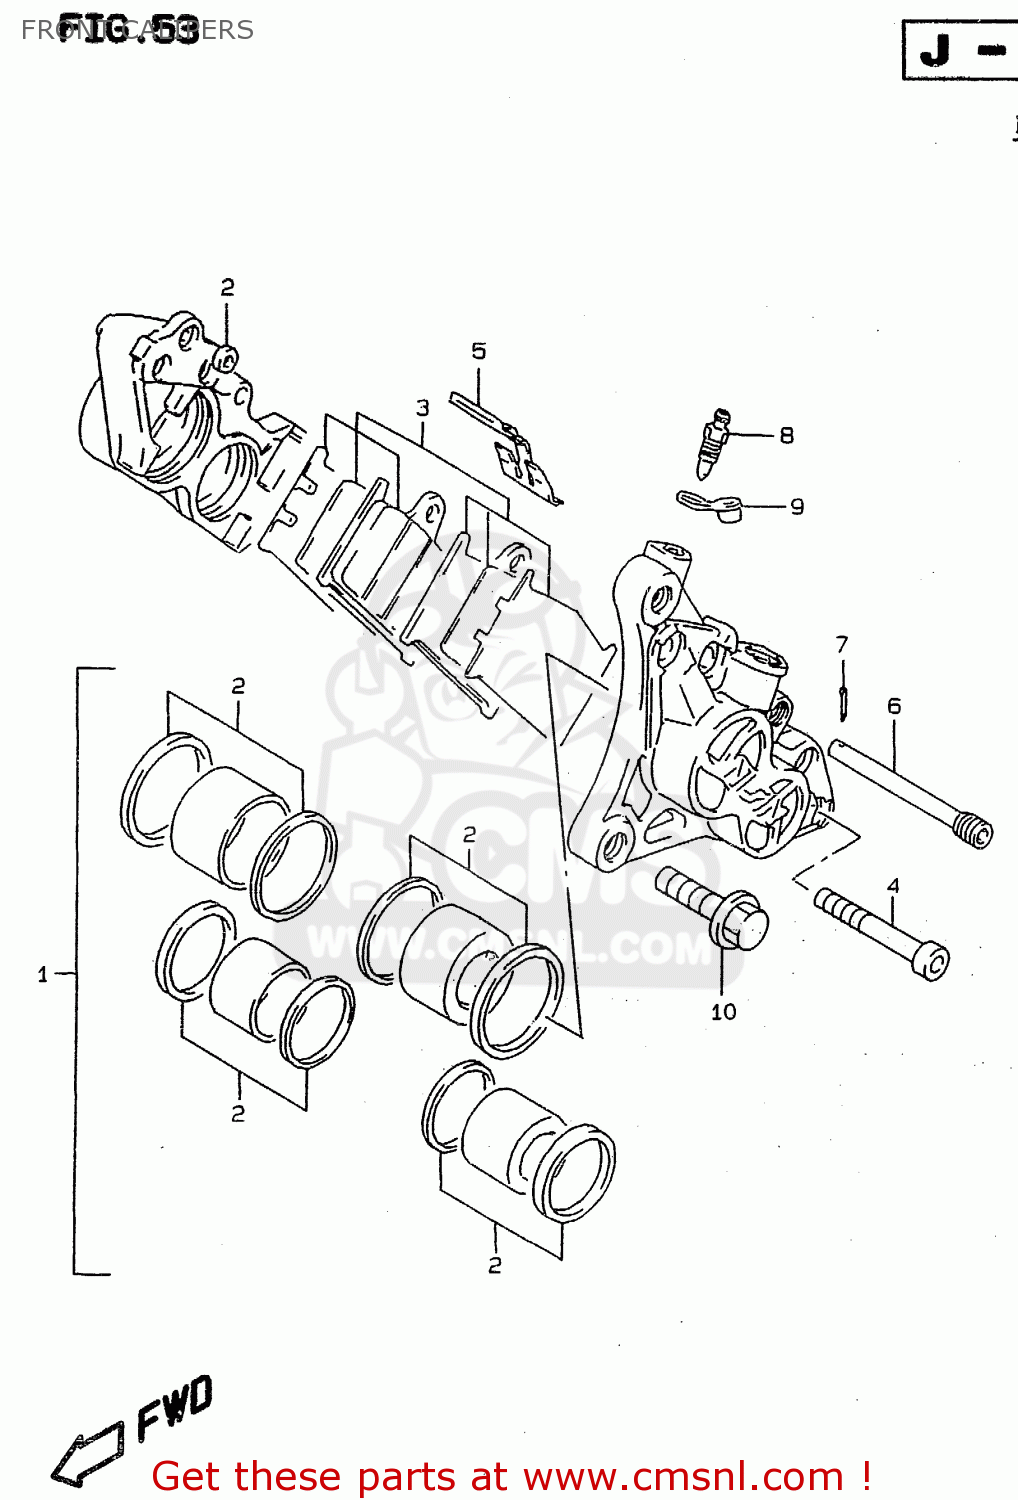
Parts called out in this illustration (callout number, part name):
1	PISTON SET
2	SEAL SET,PISTON
3	PAD & SHIM SET (NAS)
4	BOLT
5	SPRING
6	PIN,HANGER
7	PIN 16X20
8	BLEEDER
9	CAP,BLEEDER
10	BOLT
